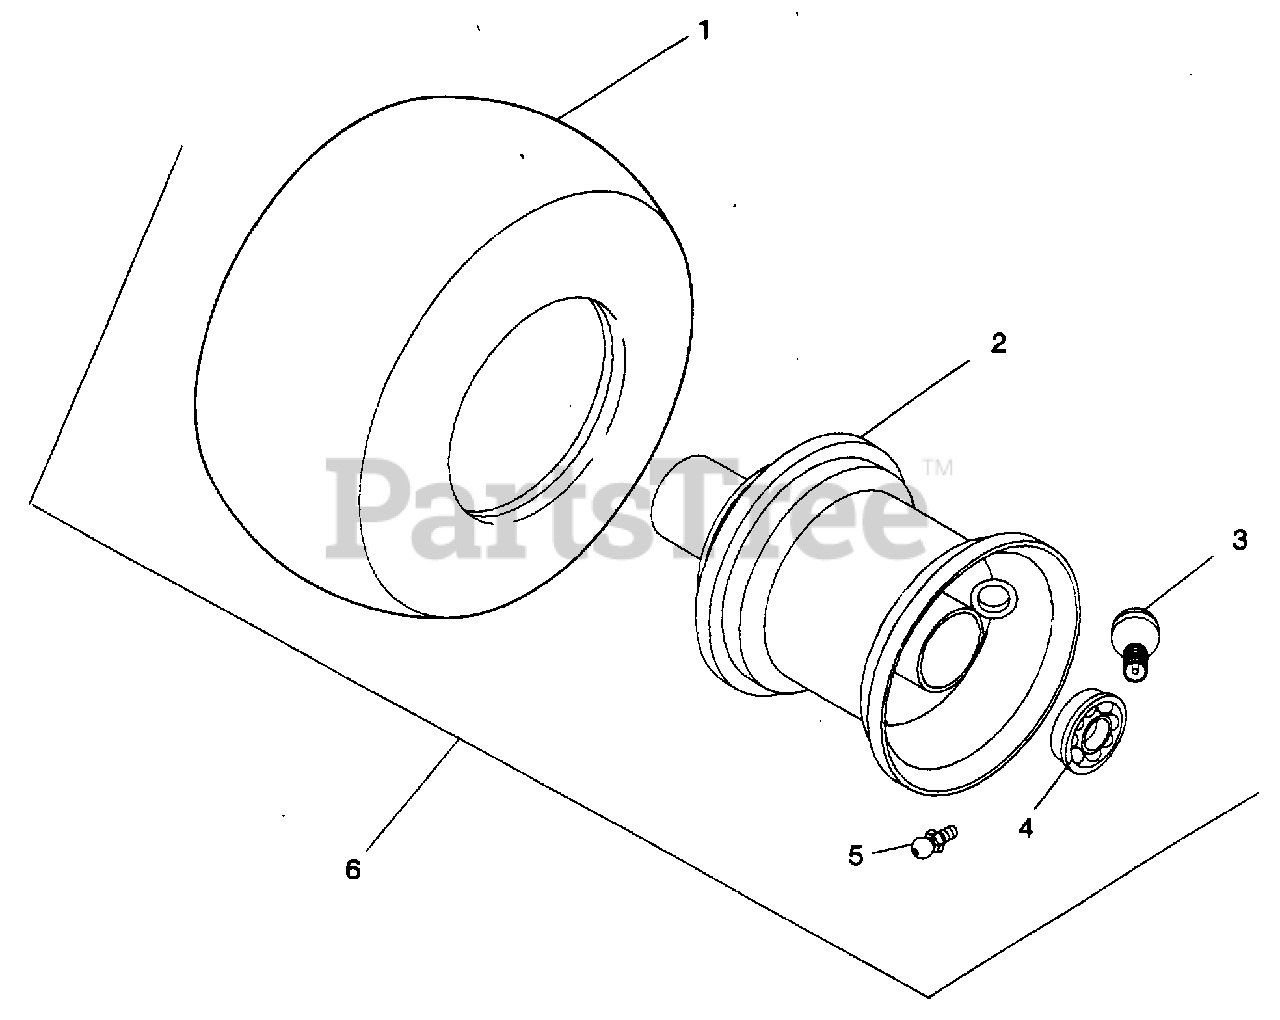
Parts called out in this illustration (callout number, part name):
1	TIRE, 13 X 6.00-6.2 PLY TURF SAVER
2	RIM-ASSY 4.5 X 3.75
3	VALVE STEM ASS'Y
4	RADIAL BEARING
5	FTG.-LUBE .25-28 X .256
6	ASS'Y, WHEEL, 13 X 6.00-6, PRO
